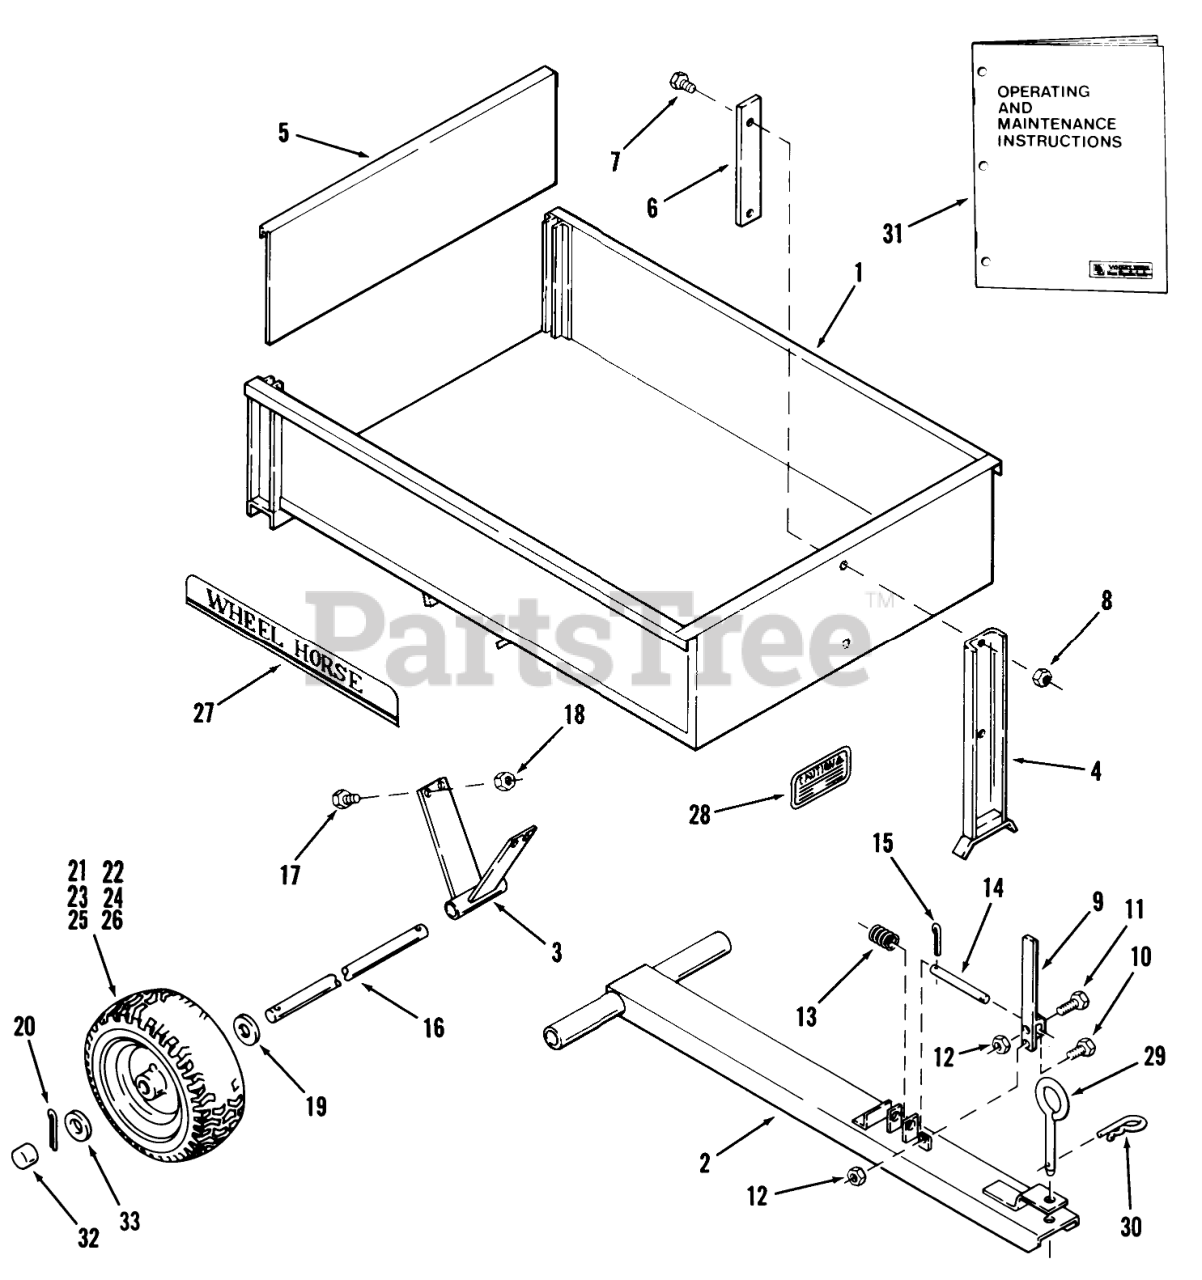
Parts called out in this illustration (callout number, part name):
13	SPRING-COMPRESSION
24	VALVE
25	BUSHING-FLANGED
27	DECAL
29	PIN-TOOL
30	Hairpin Cotter
31	Operating and Maintenance Instructions
33	WASHER-WHEEL
